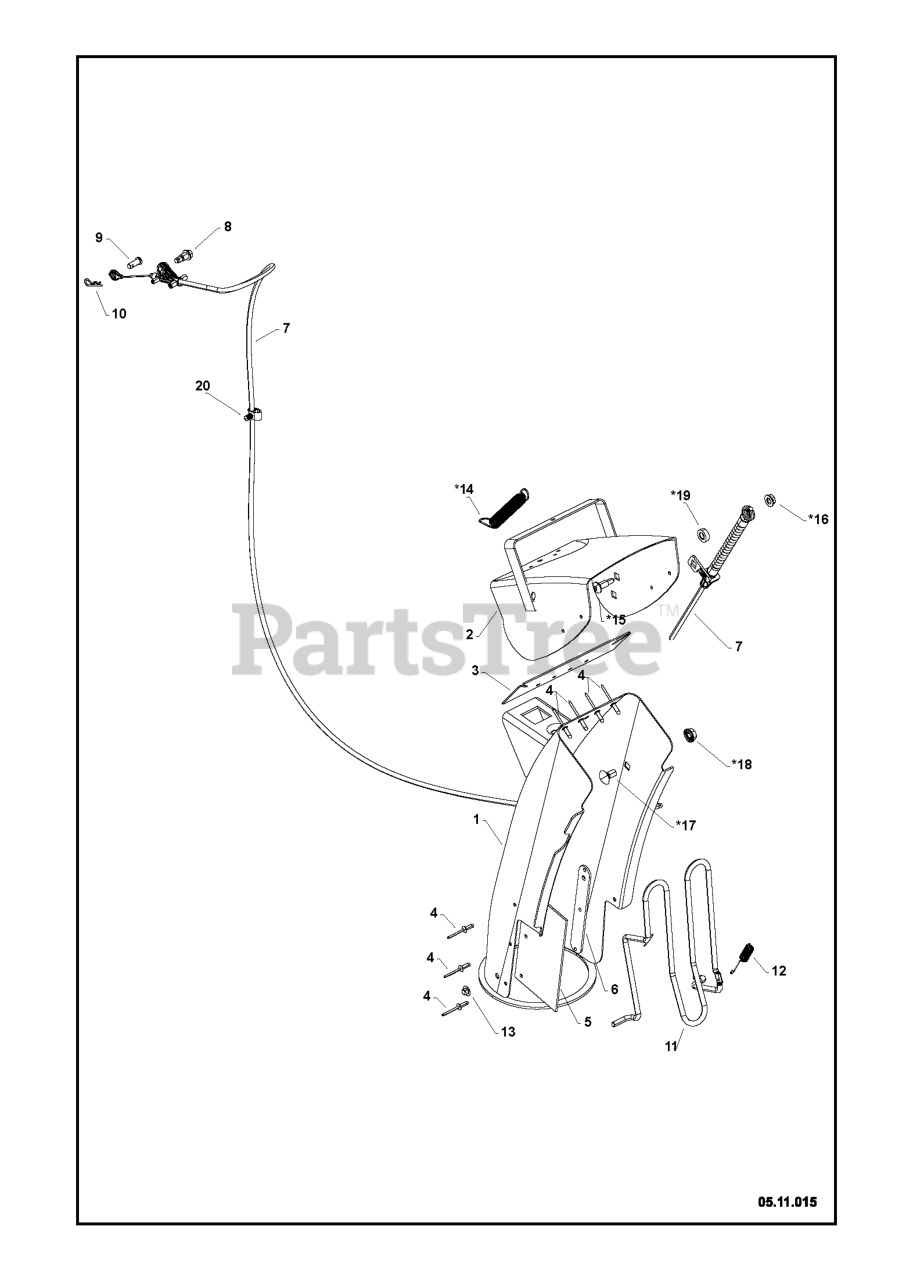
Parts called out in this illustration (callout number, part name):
1	CHUTE.WELDMENT.SNOW.ORANGE
2	ASM.CHUTE/DEFLECTOR.668
3	SEAL.DEFLECTOR
4	RIVET BLIND
5	SHIELD.SNOW.CHUTE
6	RP STRAP.SHEILD.RETAINER
8	BOLT SHOULDER_1/4-20_TRILOB
9	PIN CLEVIS .25 X ..4375
10	HAIRPIN.SOFT.ZINC.059X1.125
11	GUARD ROD CHUTE GUARD SHORT CL
12	SPRING.CHUTE.GUARD
13	NUT
20	CLIP.ROUTING DUAL
